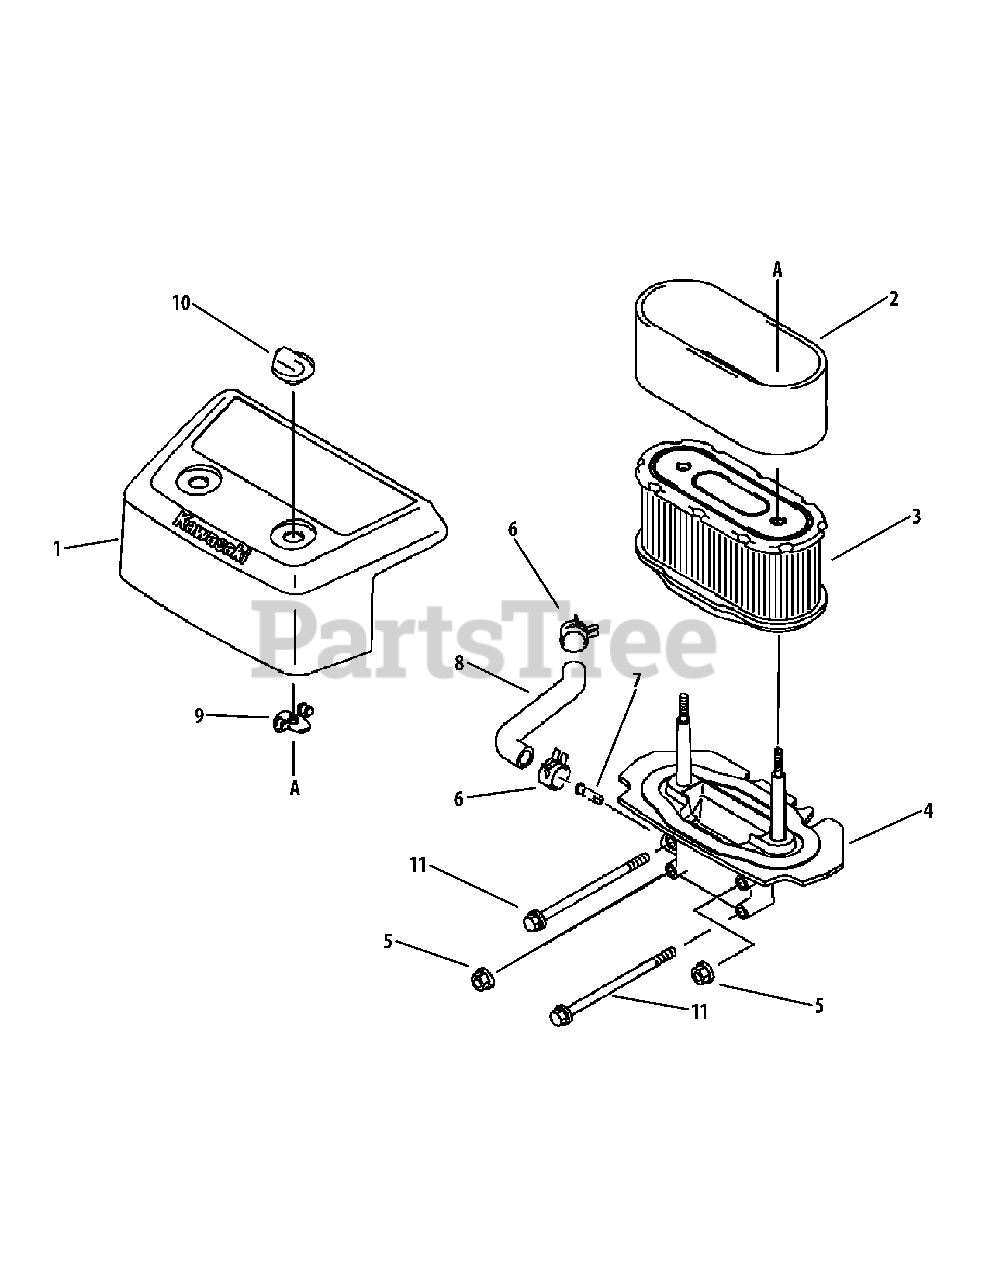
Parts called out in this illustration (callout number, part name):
1	Air Filter Case
2	Air Filter Element
3	Air Filter Element
5	Nut
6	Clamp
11	Flange Bolt
